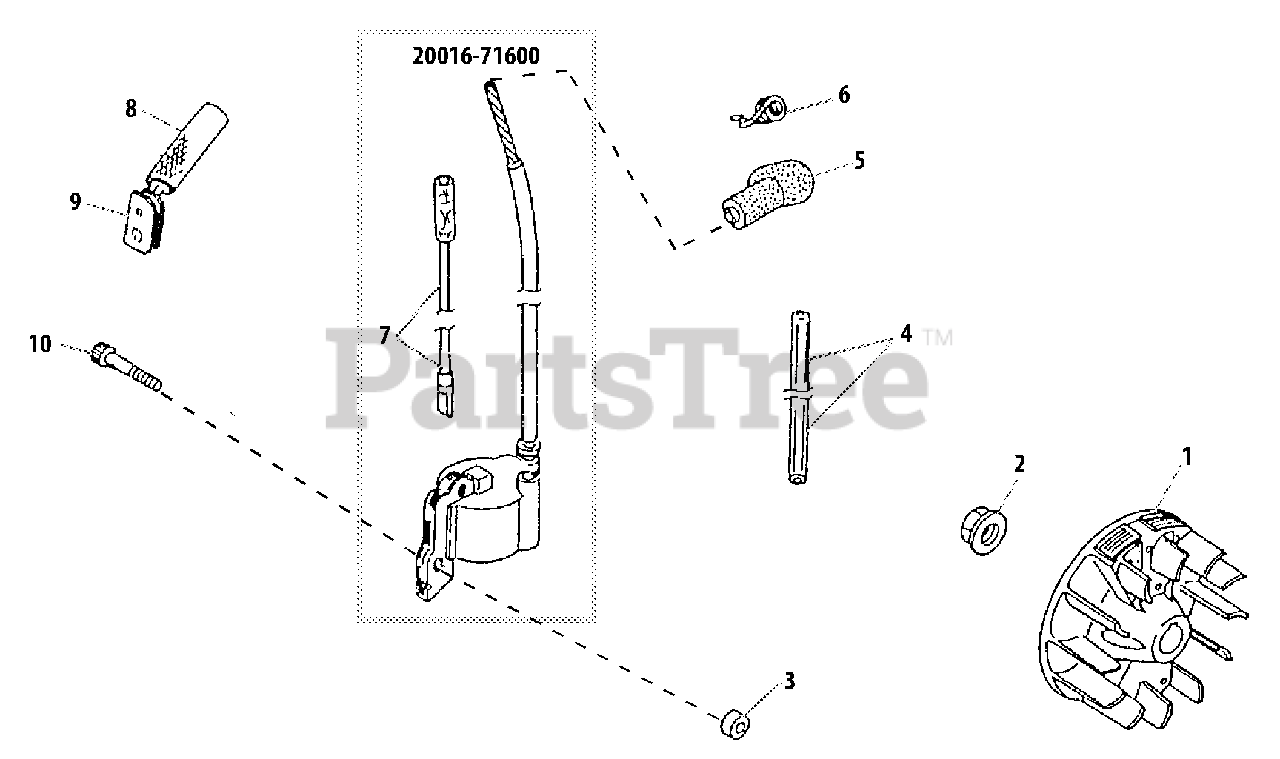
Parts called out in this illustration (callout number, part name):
1	FLYWHEEL
2	NUT M8
3	INSULATOR 4.2×11×6
4	TUBE, INSULATOR
5	CAP, SPARK PLUG
6	TERMINAL, SPARK PLUG
7	WIRE
8	TUBE, IGNITION COIL
9	GROMMET
20016-71600	IGNITION COIL ASSY
